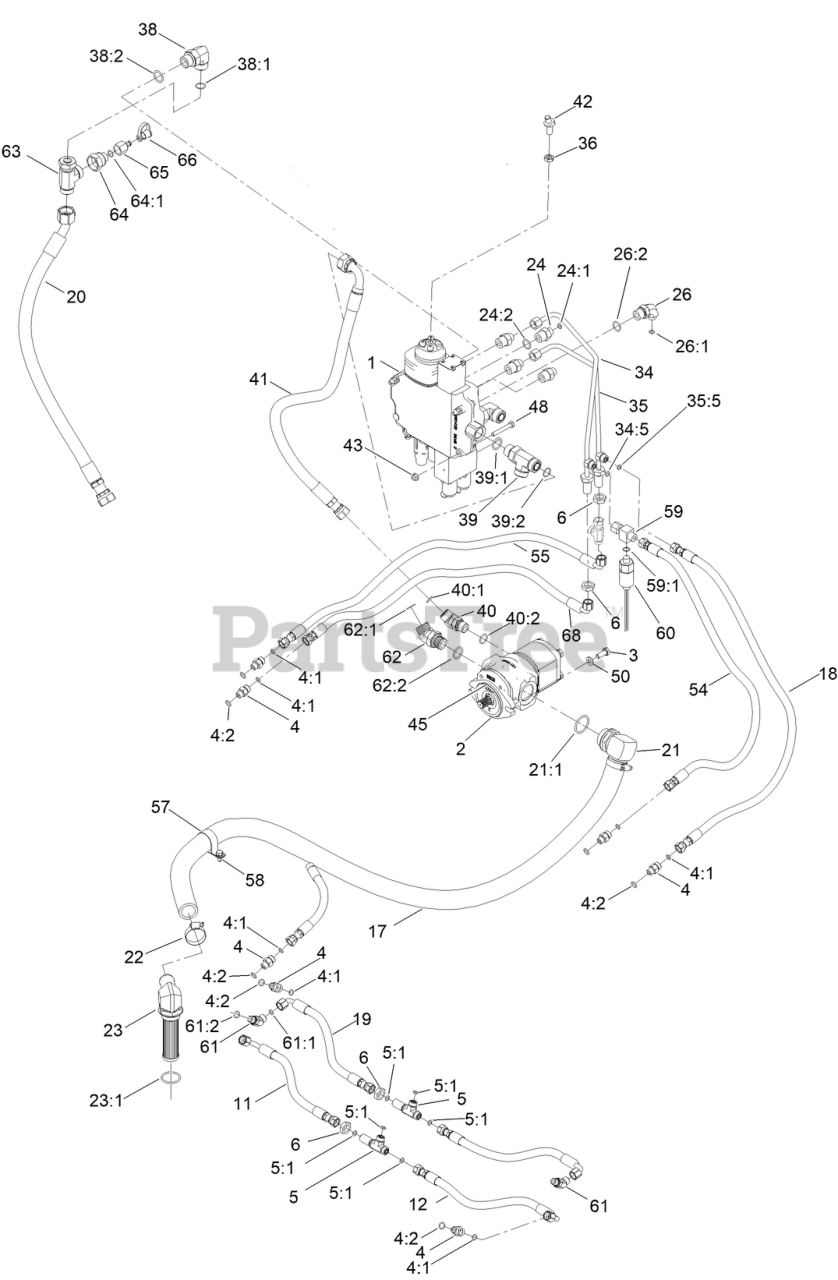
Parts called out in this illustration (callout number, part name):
1	LIFT VALVE ASM
2	GEAR PUMP ASM
3	SCREW-HH
4	FITTING-STRAIGHT
4:1	O-RING
4:2	O-RING
5	FITTING-TEE, BULKHEAD
5:1	O-RING
6	NUT-LOCK
11	HYD HOSE ASM
12	HYD HOSE ASM
18	HYD HOSE ASM
19	HYD HOSE ASM
20	HYD HOSE ASM
21	FITTING-HYD 90 SPCL
21:1	O-RING
23	STRAINER FITTING ASM
23:1	O-RING
24	FITTING-STR
24:1	O-RING
24:2	O-RING
26	FITTING-ELBOW 90
26:1	O-RING
26:2	O-RING
34	HYD TUBE ASM
34:5	O-RING
35	HYD TUBE ASM
35:5	O-RING
38	FITTING-ELBOW-90
38:1	O-RING
38:2	O-RING
39	FITTING-TEE
39:1	O-RING
39:2	O-RING
40	FITTING-HYD, 45 DEG
40:1	O-RING
40:2	O-RING
41	HYD HOSE ASM
42	SHAFT-CONTROL
43	NUT-HF, NI
45	O-RING
48	SCREW-HH
50	WASHER-FLAT
54	HYD HOSE ASM
55	HYD HOSE ASM
57	CLAMP-R
58	SCREW-HWH
59	FITTING-HYD, SPECIAL
59:1	O-RING
60	SWITCH-PRESSURE
61	FITTING-ELBOW, 45 DEG
61:1	O-RING
61:2	O-RING
62	FITTING-45 DEG
62:1	O-RING
62:2	O-RING
63	FITTING-HYD
64	FITTING-STRAIGHT
64:1	O-RING
65	FITTING
66	CAP-DUST
68	HYD HOSE ASM
